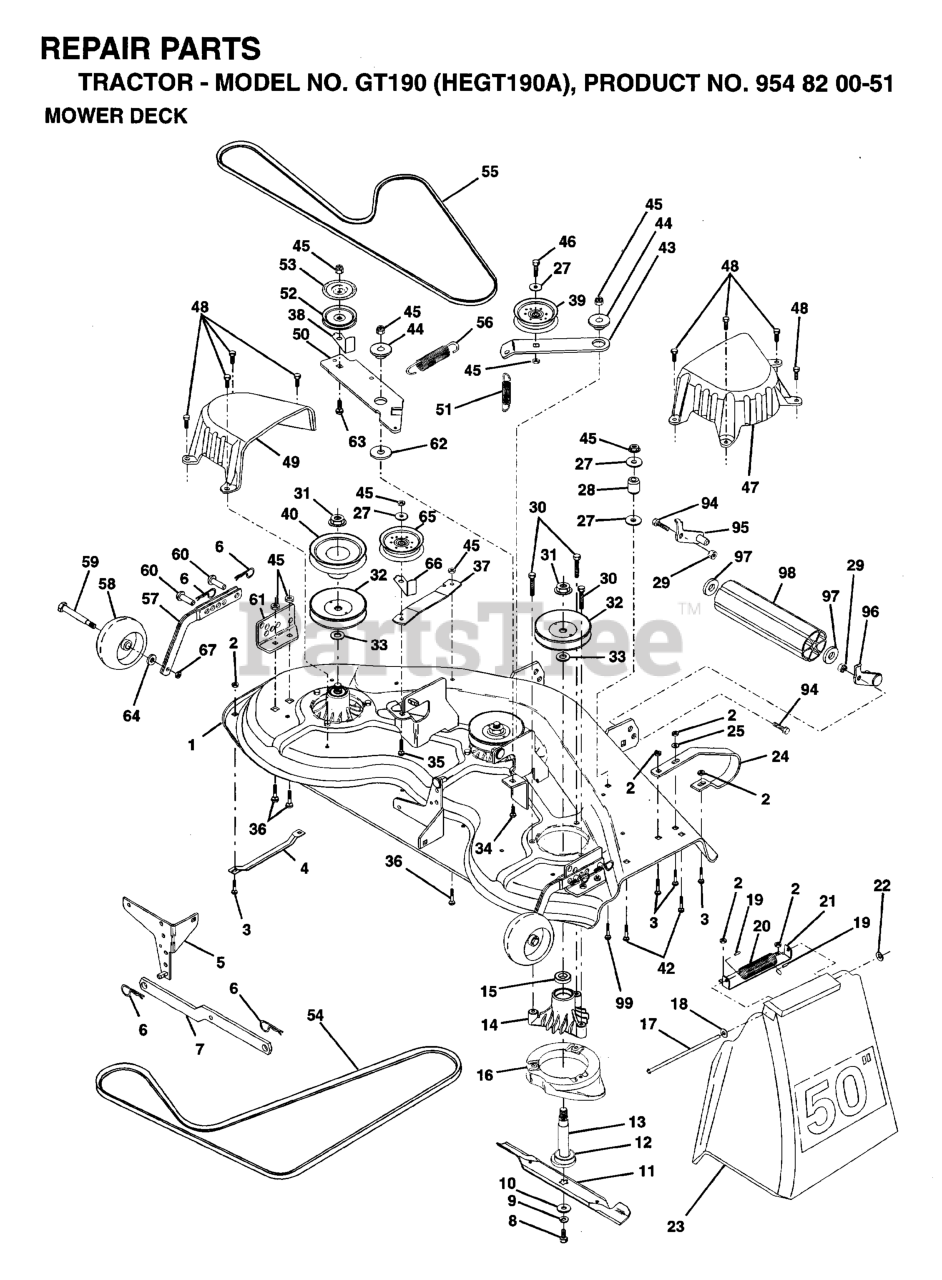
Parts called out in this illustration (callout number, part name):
1	DECK ASM MWR 50VT
2	LOCKNUT
3	BOLT.CARR.SQNK.5/16-18UNC.X3/4
4	RUNNER-LH M
5	BRACKET SWAY BAR
6	RETAINER-SPRNG RB
7	REAR SUSP ARM
8	BLADE BOLT
9	LOCKWASHER
10	WASHER.BLADE
11	BLADE.50".HI-LIFT
12	BEARING.BALL.#6204.(MANDREL)
13	SHAFT.ASM.W/BEARING
14	HOUSING.MANDREL.44/46" VENT
16	STRIPPER
17	ROD-HINGE T
18	Washer 11/32 x 5/8 x 16 Ga SD
19	CAP-SLEEVE LT
20	SPRING TORSION
21	BRACKET, DEFLECTOR
22	NUT PUSH M
23	SHIELD.DEFLECTOR.MOWER.50"BLK.
25	WASHER M
27	WASHER
28	IDLER SPRING SPACER
29	NUT
30	SCREW
31	NUT
32	MANDREL PULLEY
33	WASHER
34	BOLT.3/8-14X1.25
36	BOLT D
37	STIFFENER ARM
38	KEEPER
39	FLAT IDLER PULLEY
40	PULLEY.DRIVEN.44"
42	RP BOLT 5/16-18 X3/4 ZN/YEL GR
43	ARM.IDLER.SEC.44"
44	SPACER RETAINER
46	BOLT
47	COVER MANDRELL
48	SCREW.1/4-20X5/8
49	COVER.MANDREL.LH.44"
50	ARM.IDLER.PRIMARY
51	SPRING.SEC.44"VEN
52	PULLEY IDLER
53	SHIELD IDLER
54	V-BELT.PRMRY 46/50 VENT.BLK BK
55	BELT V SECONDARY
57	BAR.ASM.GUAGE.WHEEL
58	WHEEL GAGE DONUT
59	BOLT, SHOULDER
60	PIN.CLEVIS
61	BRACKET.GUAGE.WHEEL
62	HARDENED WASHER
63	BOLT.3/8-16X1.50
64	WASHER.5/16.FLAT.STE.STD.
65	IDLER-FLAT T
66	KEEPER
67	LOCKNUT
94	BOLT
95	BRACKET LH (A)
96	BRACKET RH (B)
97	Washer 1 17/32 X 7/8 X 16 Ga
98	NOSE ROLLER
